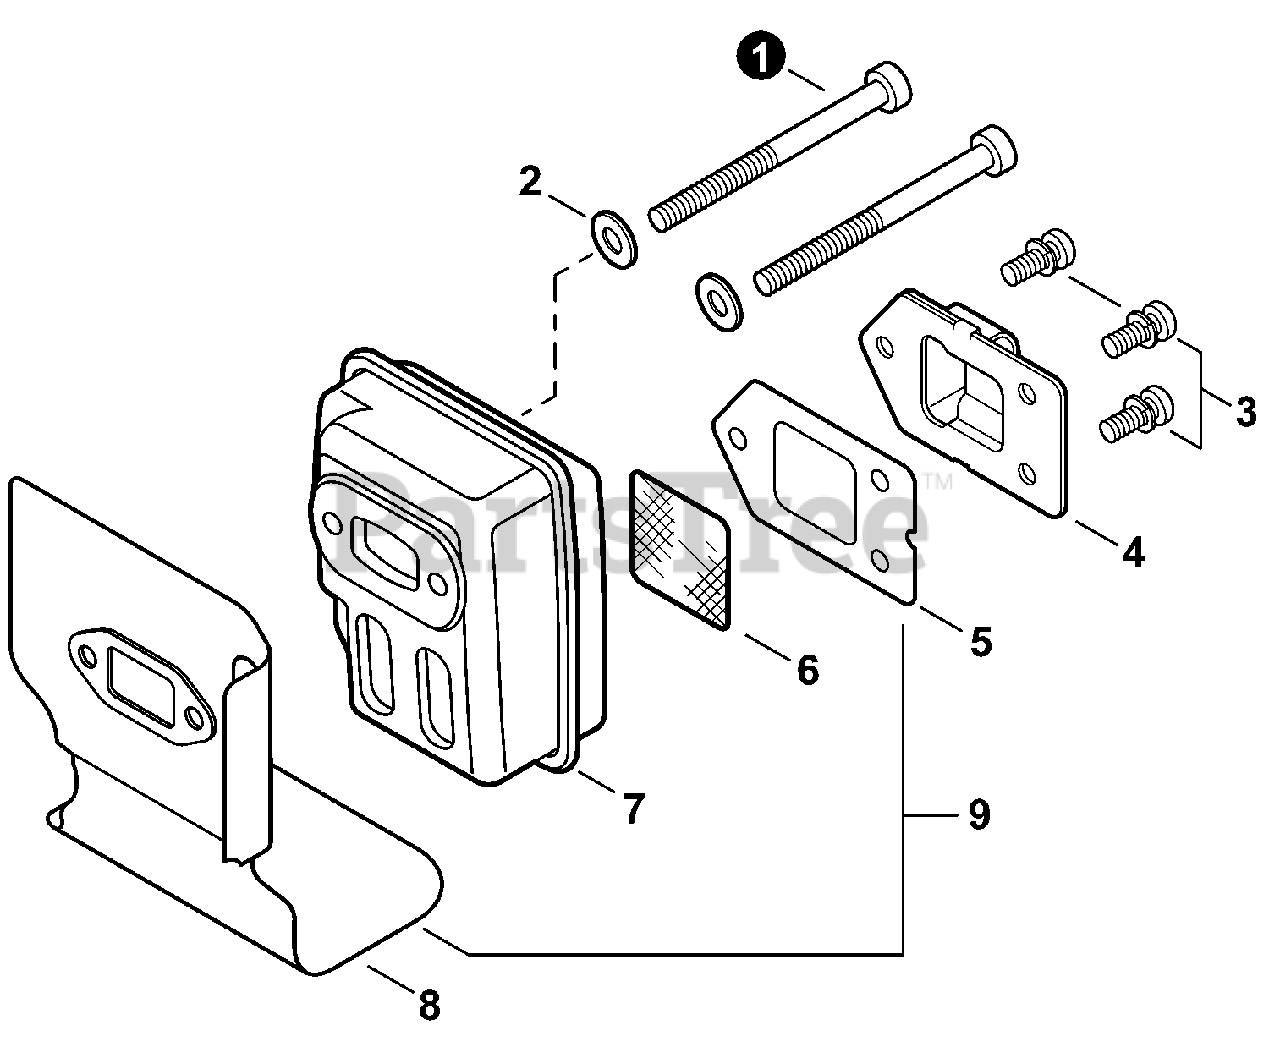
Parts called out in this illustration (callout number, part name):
1	BOLT 5×55
2	WASHER, FLAT 5.5×10×0.8
3	SCREW 4×10
4	GUIDE, EXHAUST
5	GASKET, EXHAUST
6	SCREEN, SPARK ARRESTER
8	HEAT SHIELD, EXHAUST
9	GASKET KIT
